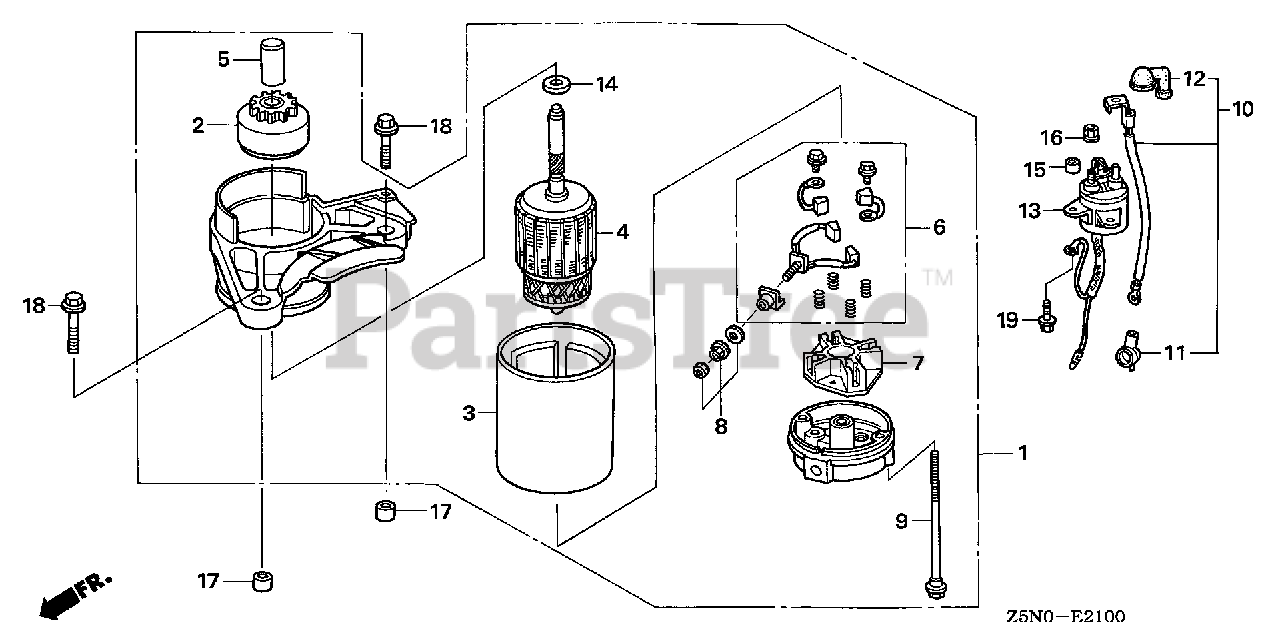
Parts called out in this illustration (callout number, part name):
1	STARTER MOTOR ASSY.
2	DRIVE ASSY.
5	STOPPER SET, PINION
6	BRUSH SET
7	HOLDER, BRUSH
8	NUT SET, TERMINAL
9	BOLT, THROUGH
14	WASHER, THRUST
17	PIN, DOWEL (10X12)
18	BOLT, FLANGE (8X35)
